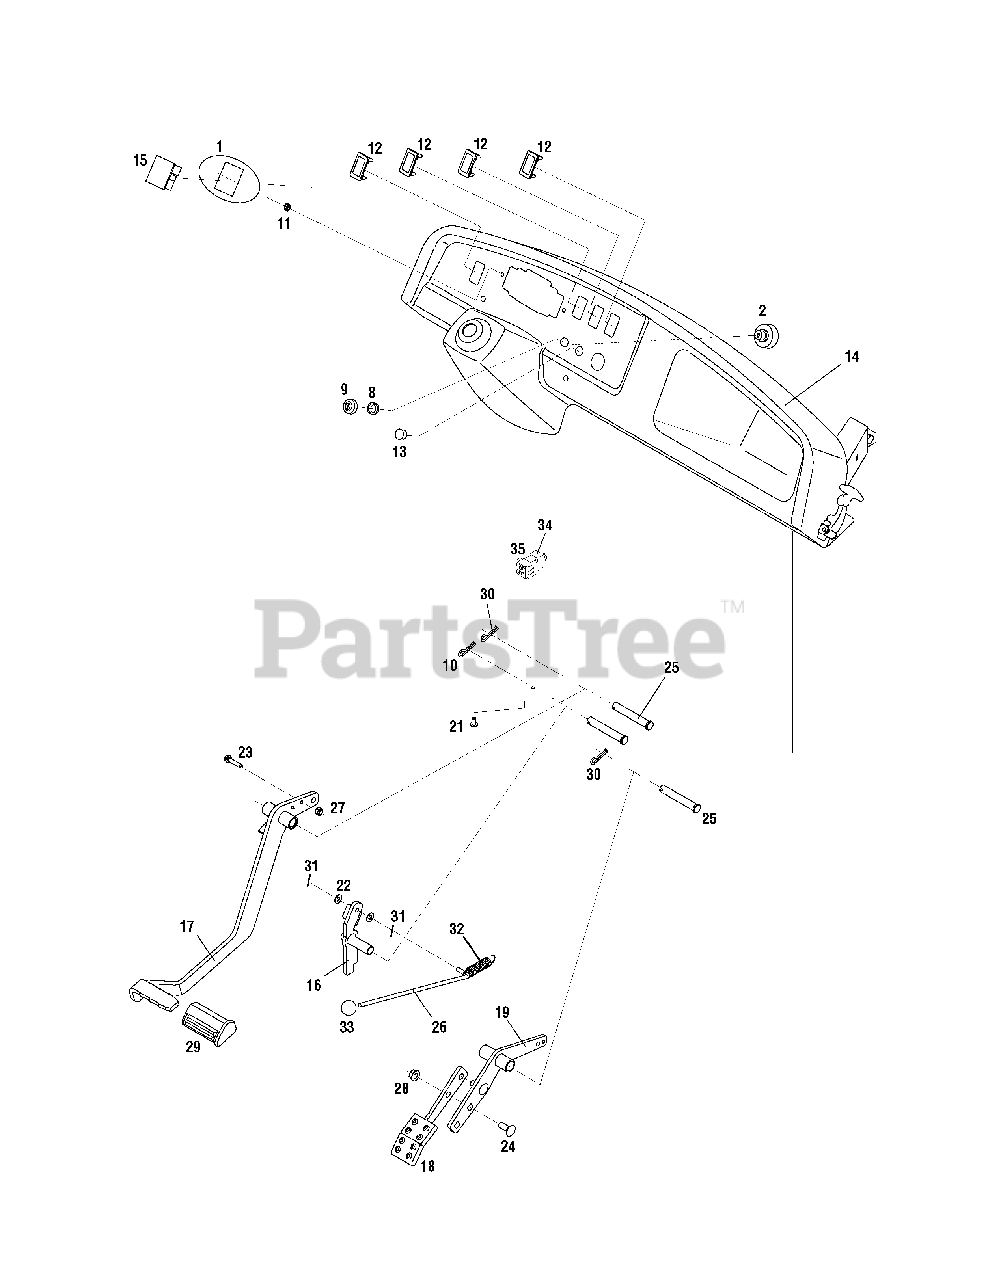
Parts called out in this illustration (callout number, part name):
1	Instrument Cover
2	Switch, Key
8	Nut, Ignition Switch, 5/8-32
9	Cap, Ignition Switch
10	Internal Cotter Pin
11	Nut, Retainer, 1/8
12	Switch Panel
13	Plug, Horn Switch
14	Dash Panel
15	Hour Meter
16	Lever, Parking Brake
17	Pedal Assembly, Brake
18	Pedal Assembly, Throttle
19	Pedal Arm Assembly, Throttle
21	Screw, Hi-Lo, 1/4-20 x .5
22	Washer, Flat .25 x .630 x .0515
23	Screw, Self-Tapping, 1/4-20x1.25
24	Bolt, Carriage, 3/8-16 x 1.0
25	Pin, Clevis.50 x 3.25
26	Rod, Brake Lock
27	Nut, Hexlock,` 1/4-20 GR 8
28	Nut, Flange Lock, 3/8-16
29	Pad, Brake Pedal
30	Pin, Cotter, 5/32 x 1.0 Lg.
31	Pin, Cotter, 1/16
32	Spring, Extension, .637 x 2.972
33	Knob, Ball
34	Cover, Protective
35	Snap Mount Switch, Interlock
